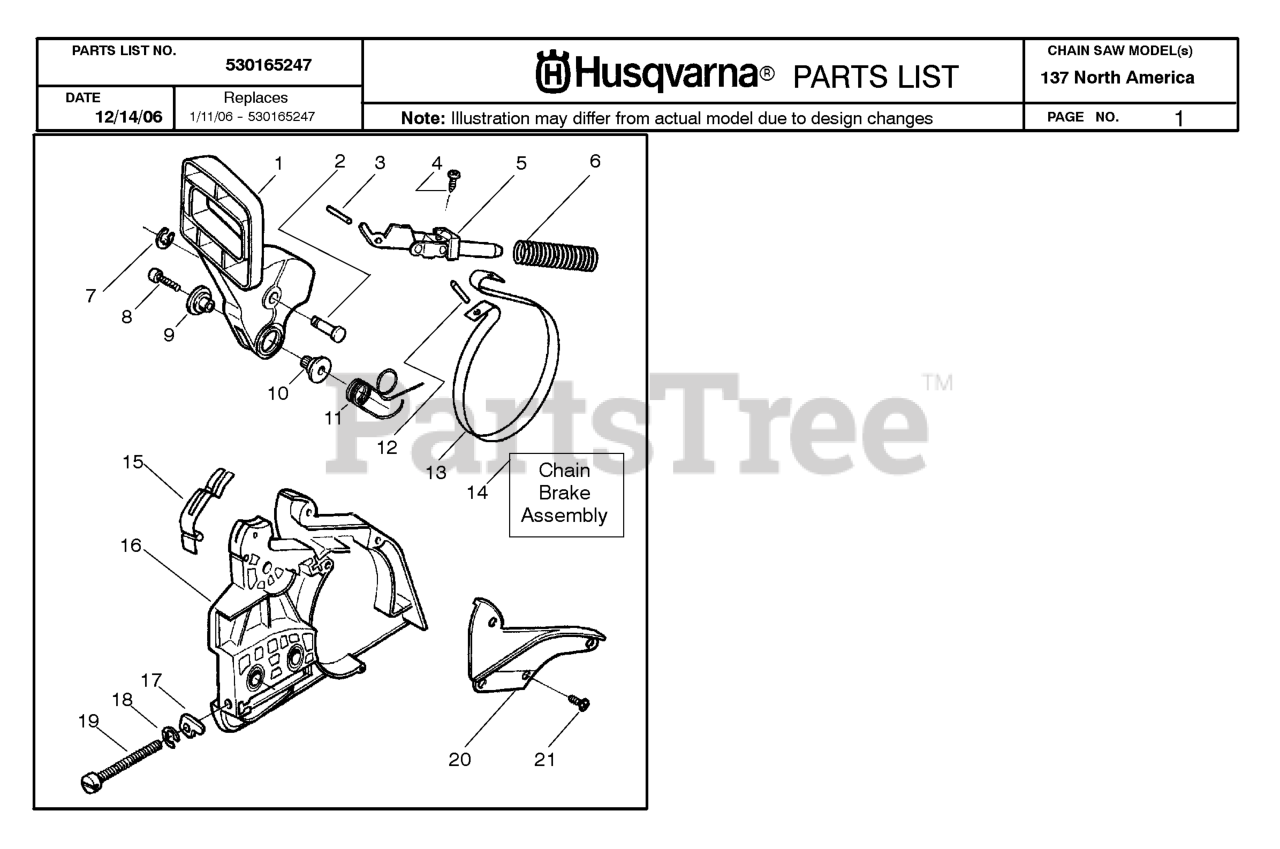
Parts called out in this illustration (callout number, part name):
4	SCREW
5	FRONT LINK ASSY
6	%COMPRESSION SPRING
9	JOURNAL, RIGHT
10	SHAFT PIVOT
11	SPRING,BRK HDL 36/41
13	BRAKE BAND
14	CHAIN BRAKE ASM.
15	SPRING-POSITION
16	CLUTCH COVER
17	ADJUST PIN,BAR 36/41
19	BAR ADJUSTING SCREW
20	CHAIN BRAKE COVER
21	SCREW
